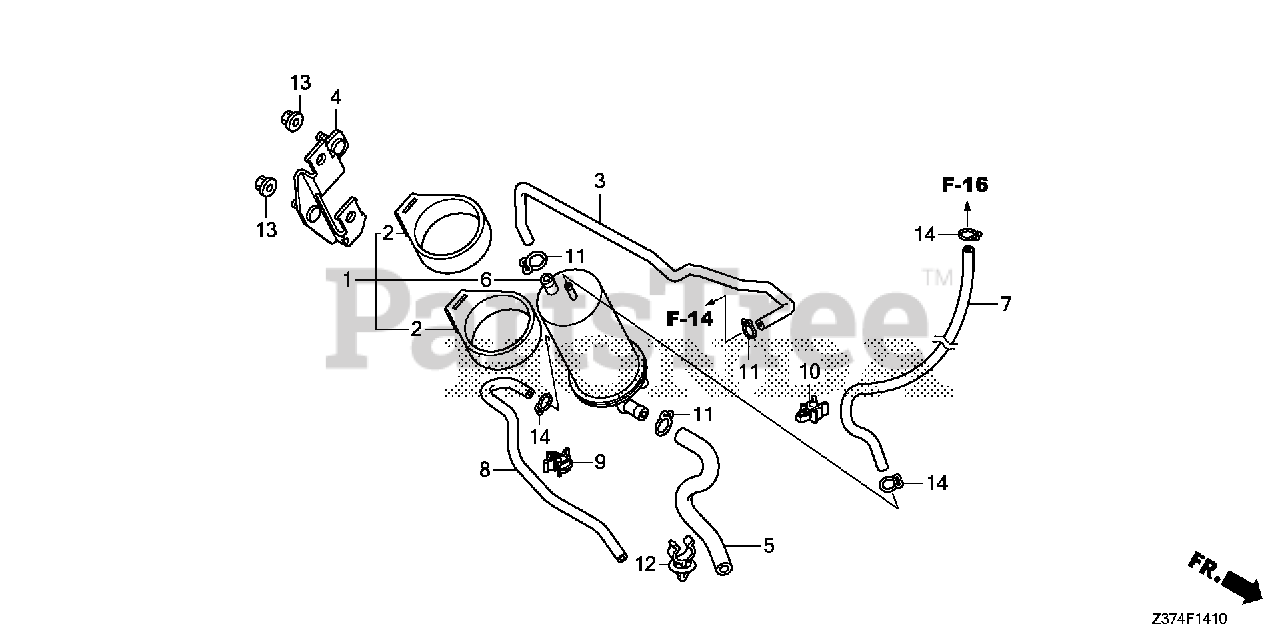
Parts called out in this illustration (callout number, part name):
1	CANISTER ASSY.
2	RUBBER, CANISTER MOUNTING
3	TUBE, CANISTER PURGE
4	STAY, CANISTER
5	TUBE, CANISTER AIR
6	CANISTER ASSY.
7	TUBE, CANISTER CHARGE
8	TUBE, CANISTER DRAIN
9	CLIP, WIRE HARNESS
10	CLIP, TUBE
11	CLIP, PURGE TUBE
12	CLAMP, SUB-TUBE (NOT AVAILABLE)
13	NUT, FLANGE (6MM)
14	CLIP, TUBE (B7)
